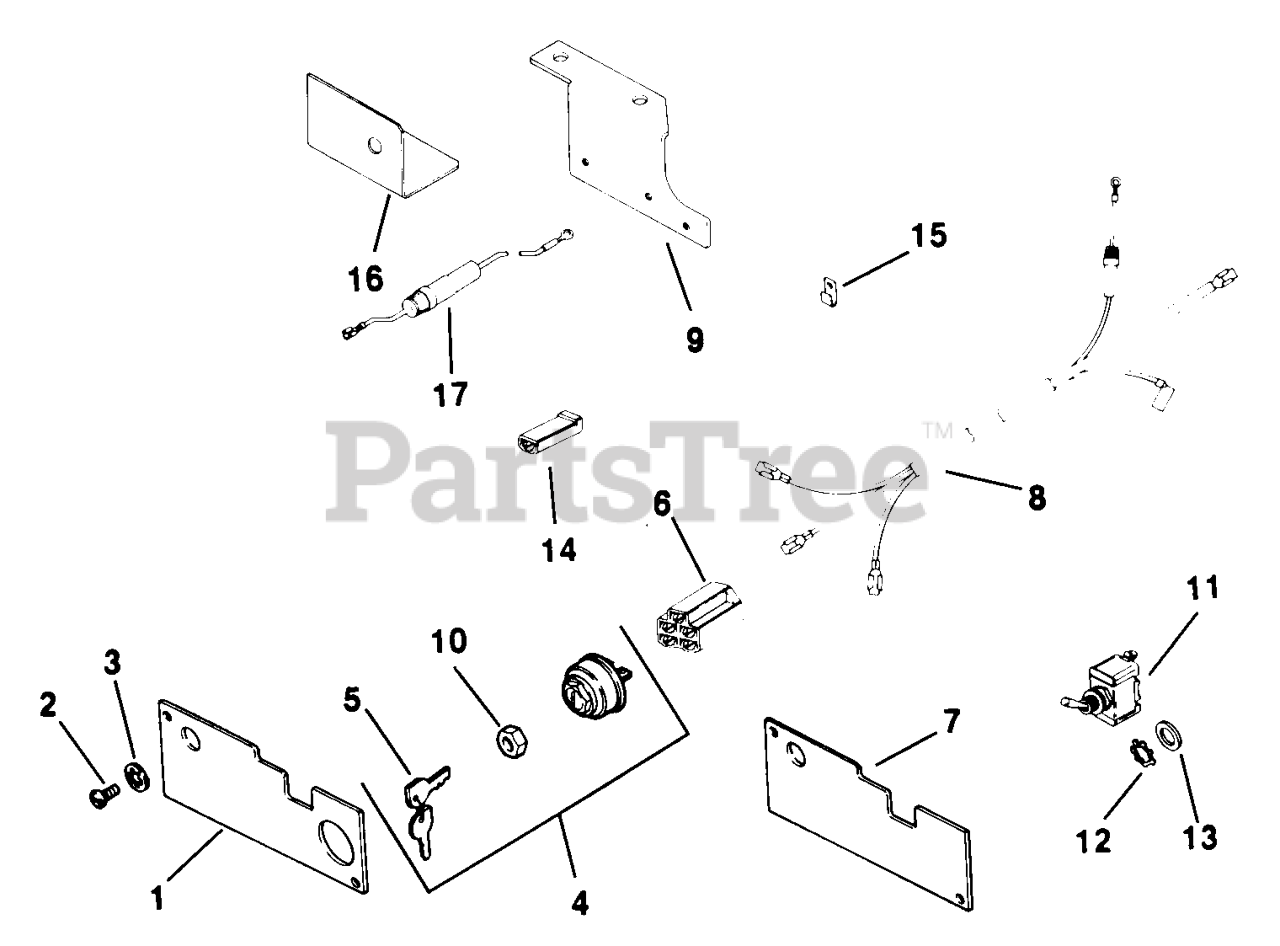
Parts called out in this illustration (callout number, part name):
1	PANEL - DISCONTINUED
2	SCREW - DISCONTINUED
4	SWITCH ASSY, KEY (KM)-USE 25 099 32-S
5	KEY, SET -USE 48 340 01-S
6	CONNECTOR
8	HARNESS
10	NUT, KEY SWITCH
